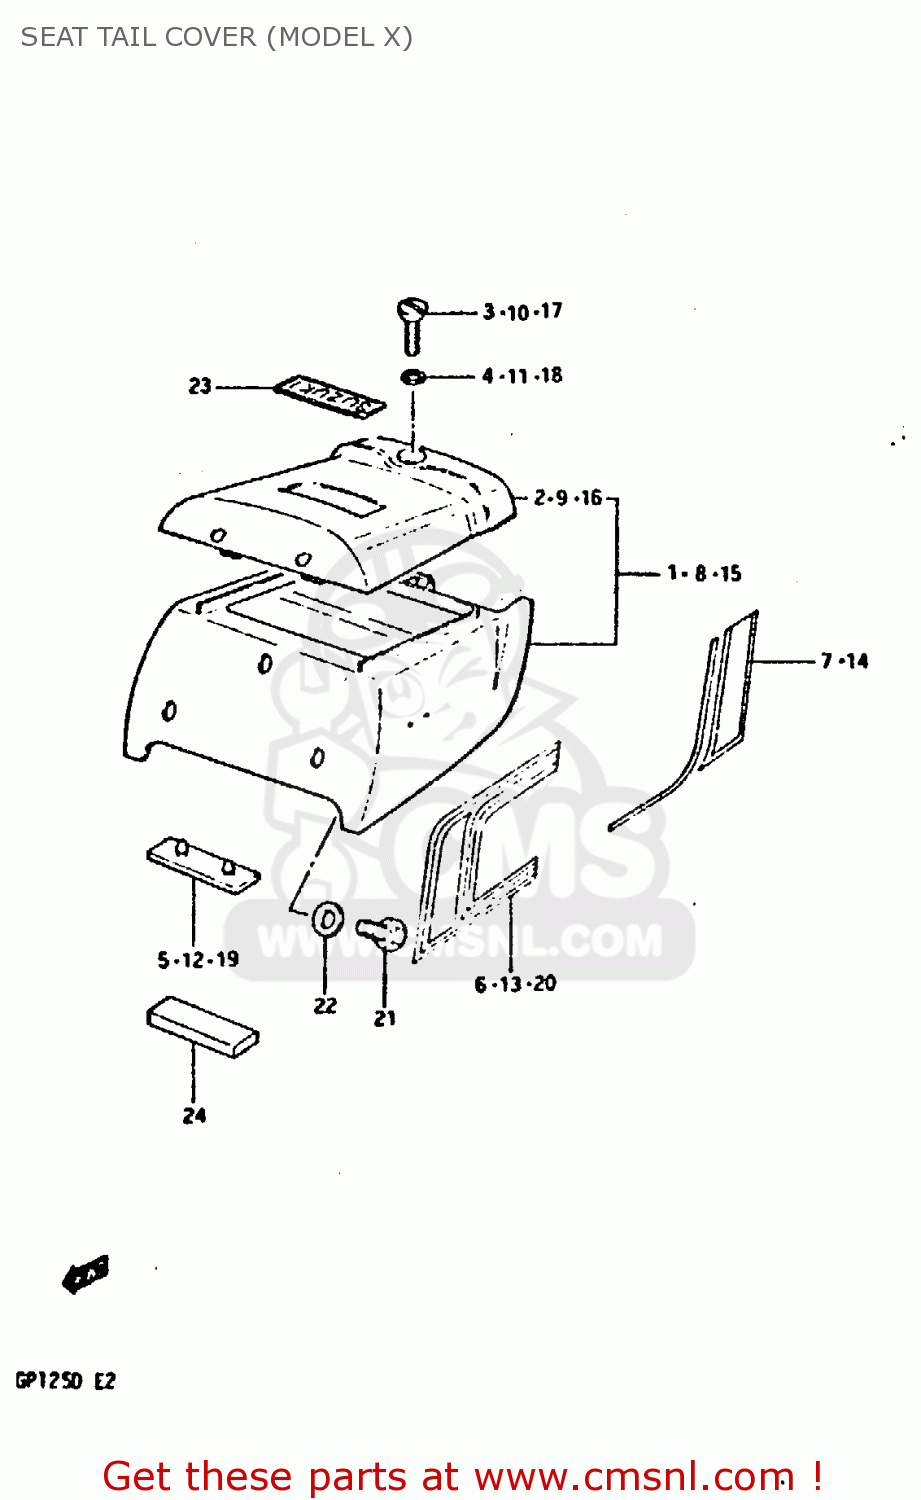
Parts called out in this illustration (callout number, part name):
1	COVER, SEAT TAIL
2	LID
3	KNOB,SEAT TAIL COVER
4	E RING
5	CUSHION
6	TAPE SET
8	COVER, SEAT TAIL
9	LID
10	KNOB,SEAT TAIL COVER
11	E RING
12	CUSHION
13	TAPE SET
15	COVER SET, TAIL (BLACK)
16	LID (BLACK)
17	KNOB,SEAT TAIL COVER
18	E RING
19	CUSHION
20	TAPE SET
21	BOLT, UPPER
22	WASHER
23	EMBLEM,CARB INSPECTION CAP
24	CUSHION,SEAT TAIL
